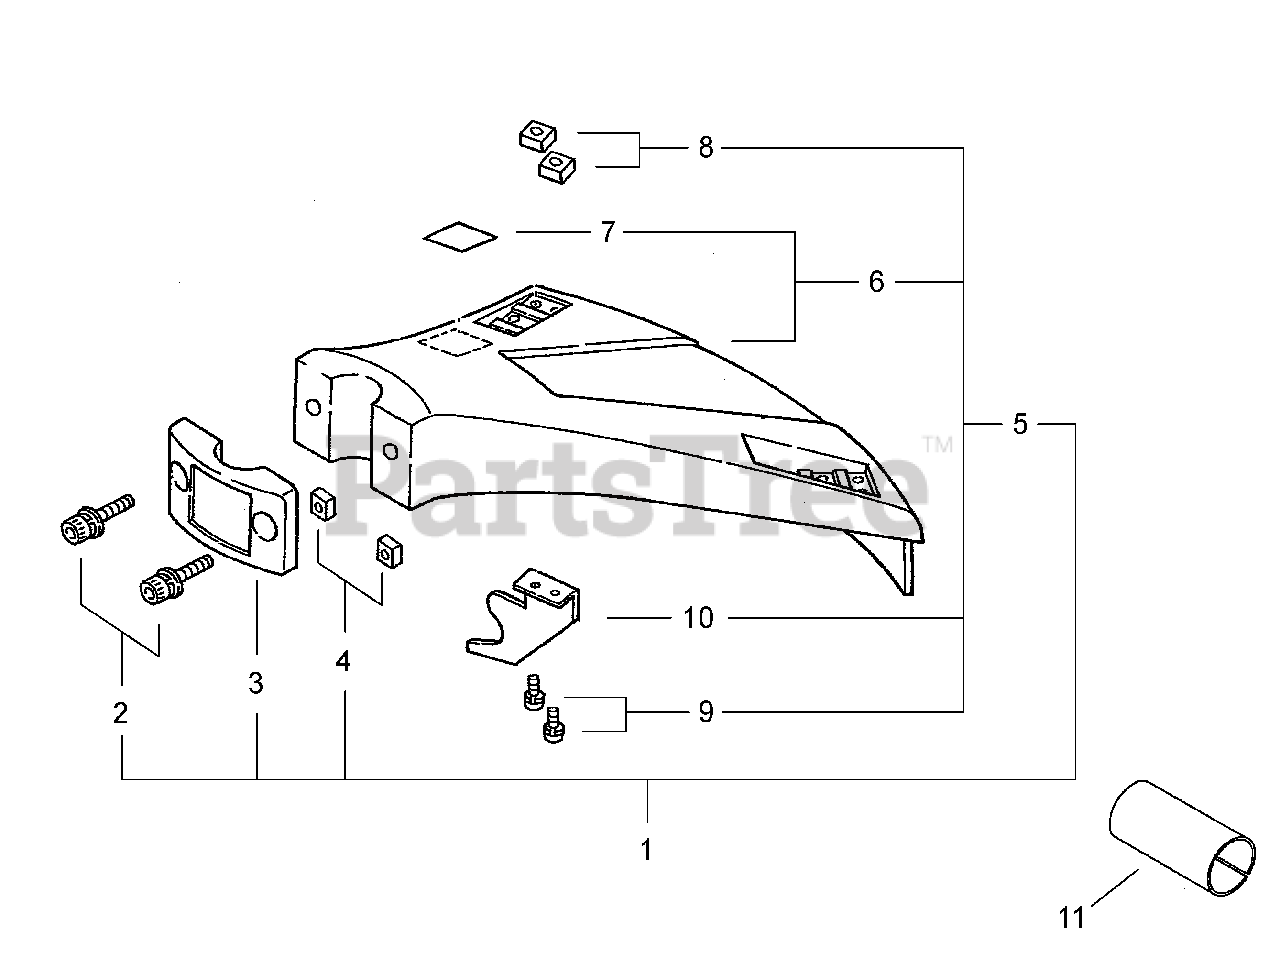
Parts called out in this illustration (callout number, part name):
1	DEBRIS SHIELD ASSY
2	BOLT M5×25
3	CAP
4	NUT M5
5	DEBRIS SHIELD KIT
6	SHIELD, DEBRIS
7	LABEL, CAUTION
8	NUT
9	SCREW
10	CUTTER, LINE
